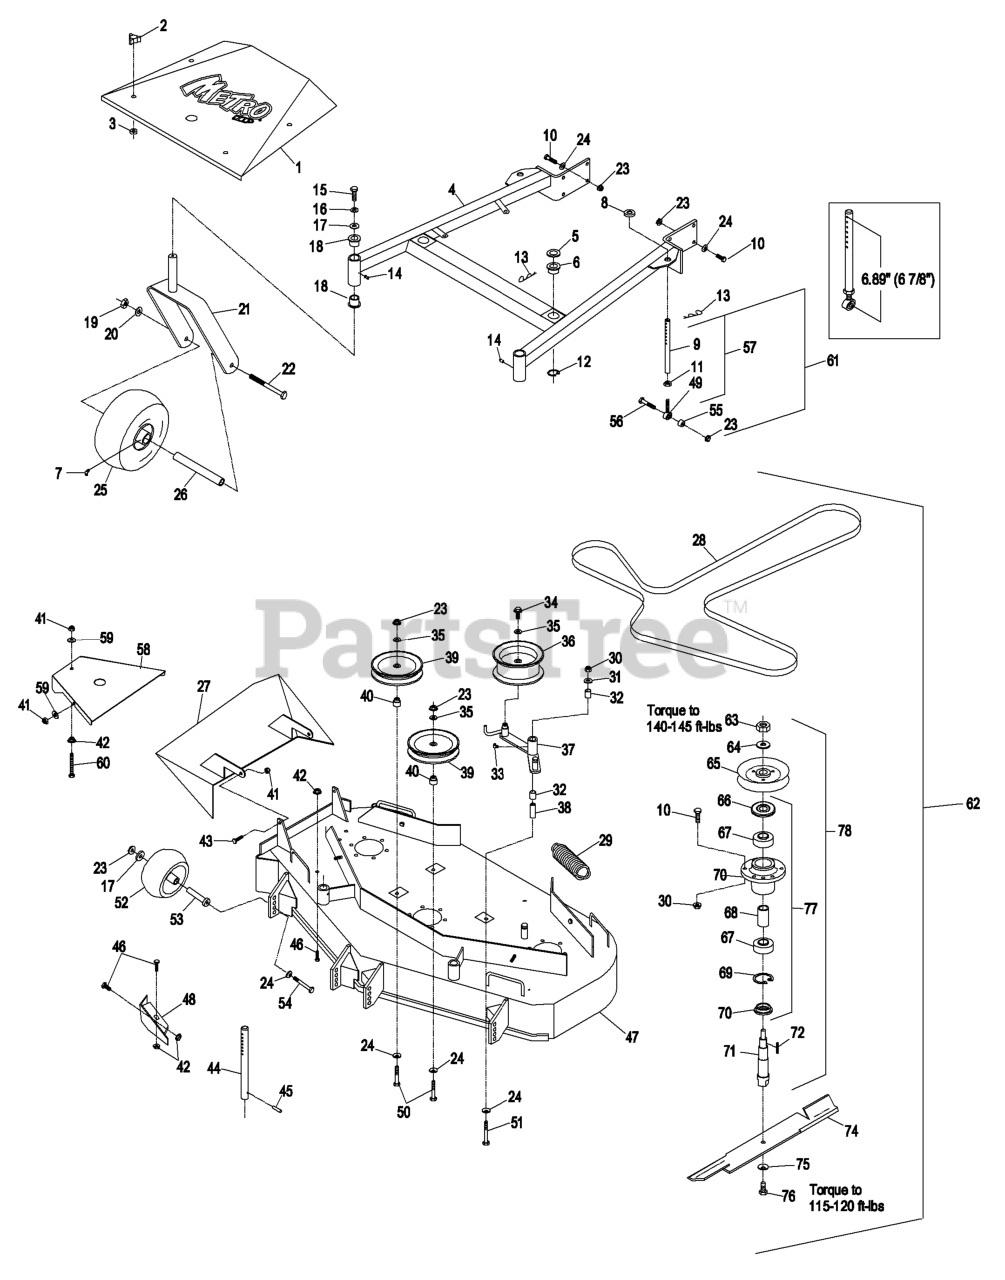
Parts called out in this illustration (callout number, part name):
1	SHIELD W/DECAL,MHP48
2	KNOB-3 PRONG
4	DECK SUPPORT W/BSHGS 48"
5	SPACER-DECK SUPPORT
6	BUSHING-DECK
7	FITTING-GREASE
9	LINK,SUPPORT
10	SCREW-HH
11	NUT-HEX
12	RING-RETAINING
13	PIN,HAIR COTTER
14	FITTING-GREASE
15	SCREW-HH
16	WASHER-LOCK
18	BEARING-FLANGED
19	NUT-HH
20	WASHER-LOCK
22	SCREW-HH
23	NUT-HHF, WHIZ
24	WASHER-BELLEVILLE
26	SPACER FRONT CASTER
27	WLD,DISCHARGE CHUTE 36/48
28	BELT - V, B
30	NUT-LOCK, NI
31	WASHER-FLAT
32	SLEEVE-BEARING
33	FITTING-GREASE, 90 DEG
34	SCREW-HHF
35	WASHER-FLAT
38	BUSHING-PIVOT, IDLER
39	PULLEY-IDLER
40	BUSHING-IDLER
41	NUT-LOCK, NI
43	SCREW-HH
44	ROD,DECK SUPPORT
46	SCREW-HH
47	ASM,DECK W/DECALS TTHP/MH
49	BALLJOINT
50	SCREW-HH
51	SCREW-HH
52	ROLLER-SCALP, ANTI
53	BUSHING-ROLLER
54	SCREW-HH
56	SCREW-HH
58	SHIELD,BELT
59	WASHER-FLAT
60	BOLT,TAP HH
62	Assy, Cutting Deck Complete
65	SHEAVE,W/HUB 5.72
66	GUARD-BEARING, TOP
67	BEARING-JACKSHAFT
68	SPACER-BEARING
69	RING-SNAP
70	SPACER-GUARD, BOTTOM
71	SPINDLE,SHAFT
72	KEY-RECTANGLE
75	WASHER-SPRING
76	SCREW-CAP
79	KIT, SP CASTER WHEEL REPL
